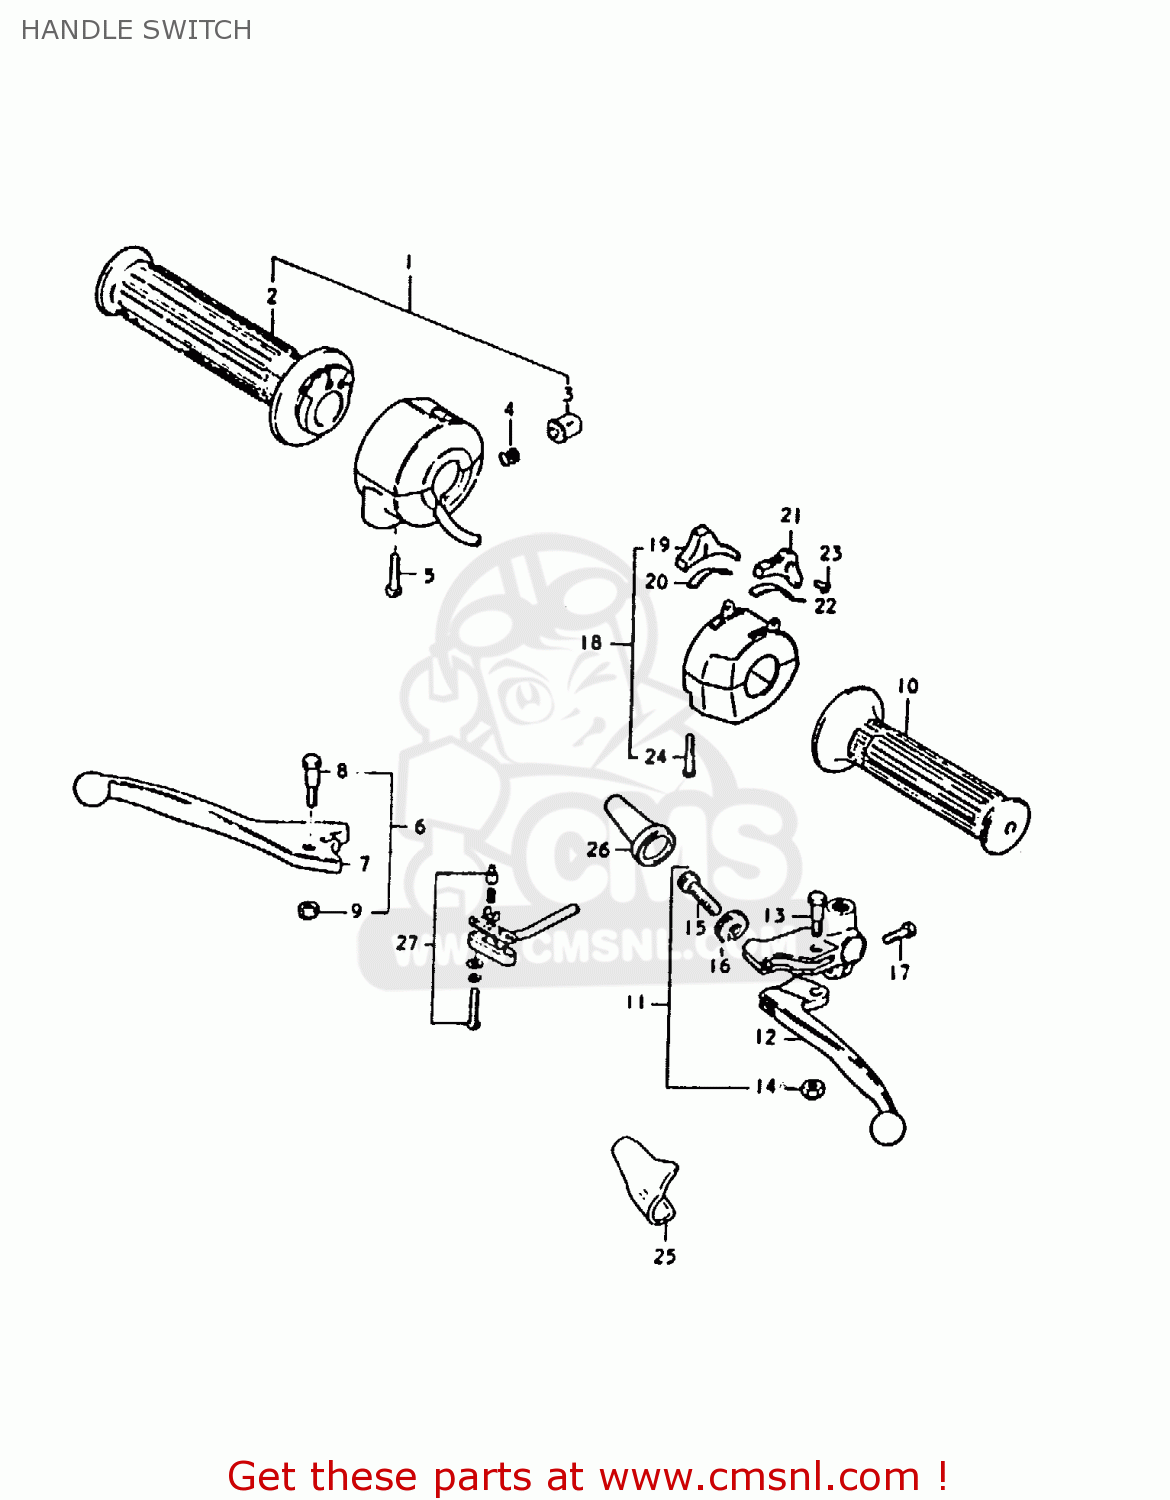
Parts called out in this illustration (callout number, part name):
1	GRIP ASSY, THROTTLE
2	GRIP,THROTTLE
3	BUTTON
4	SPRING
5	SCREW
6	LEVER ASSEMBLY,BRAKE
7	LEVER,BRAKE
8	BOLT,LEVER
9	NUT 6MM
10	GRIP,L
11	LEVER ASSEMBLY
12	LEVER,CLUTCH
13	BOLT,LEVER PIVOT
14	NUT 6MM
15	ADJUSTER,CABLE
16	NUT,CABLE ADJUSTER
17	BOLT
18	SWITCH ASSEMBLY,HANDLE,LEFT
19	KNOB,HANDLE SWITCH
20	PLATE,SWITCH KNOB
21	KNOB,DIMMER SWITCH
22	SPRING
23	SCREW
24	SCREW
25	COVER,CLUTCH LEVER
26	BOOT,CLUTCH CABLE
27	SWITCH ASSY,STOP
